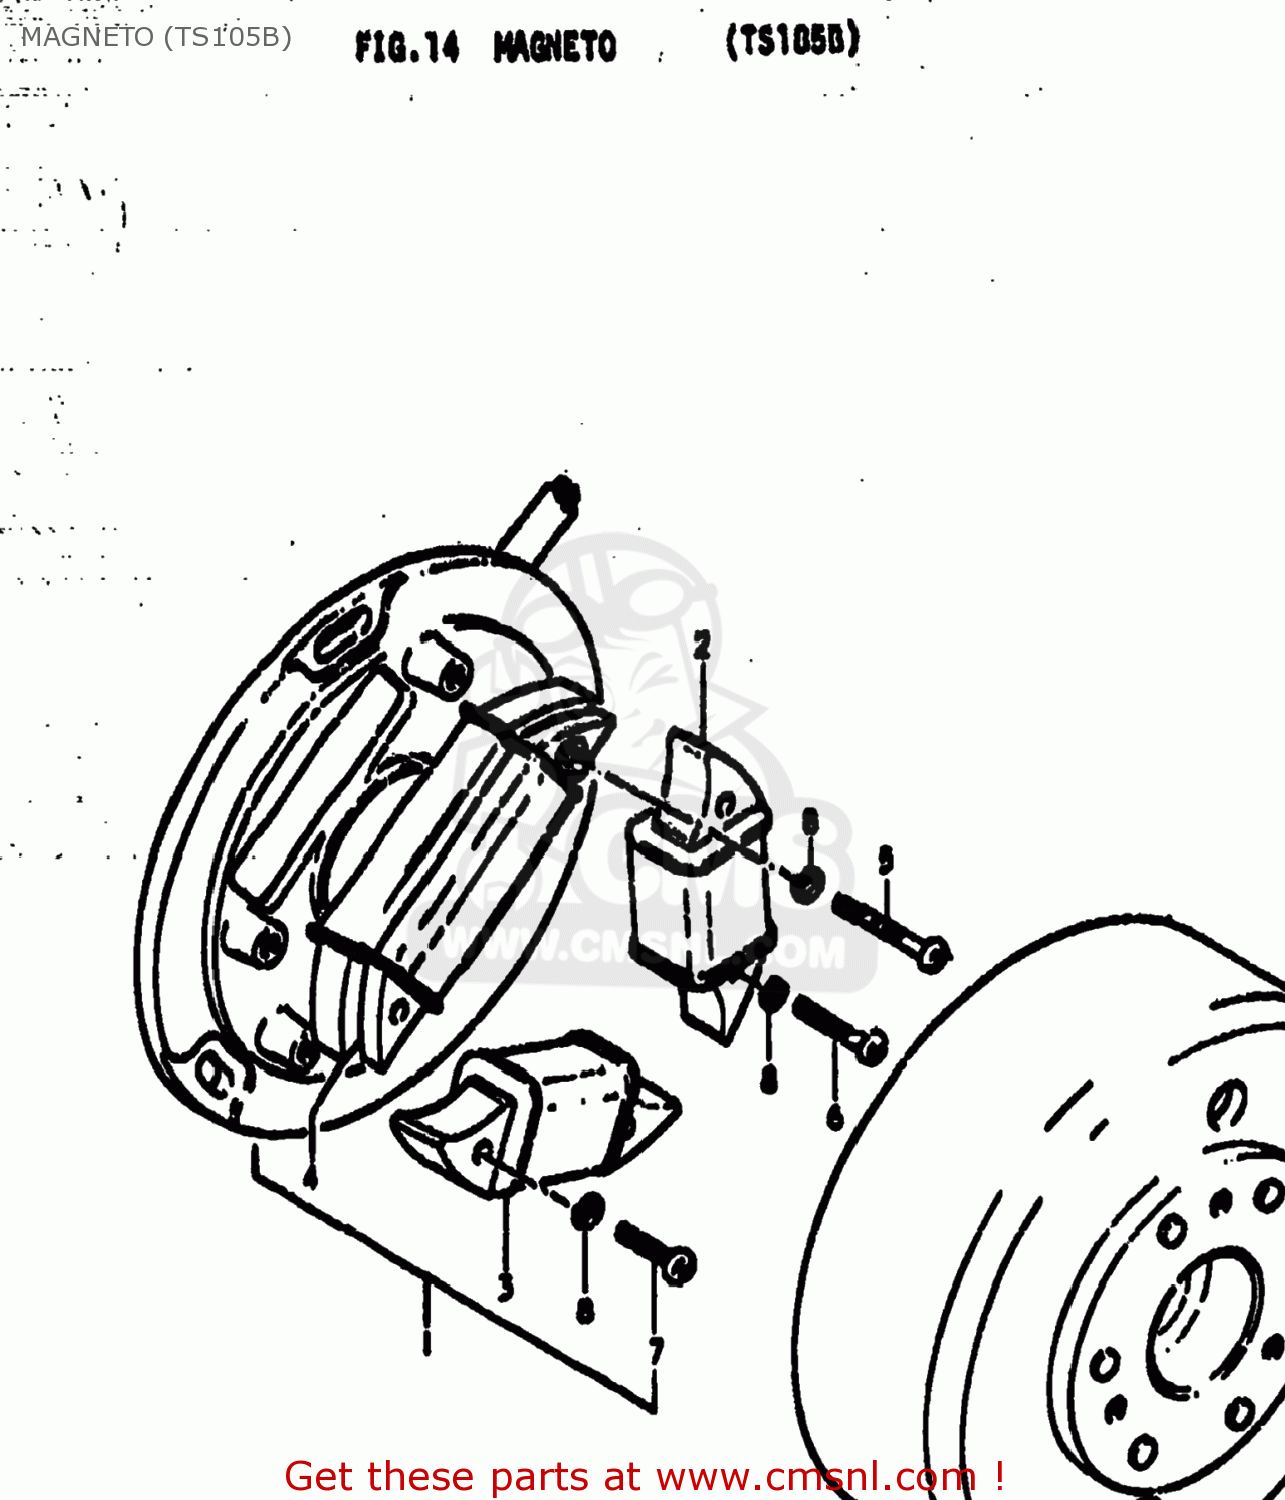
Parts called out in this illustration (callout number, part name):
1	STATOR ASSEMBLY
2	COIL,LIGHTING
3	COIL
4	COIL,IGNITION
5	SCREW
6	SCREW
7	SCREW 5X20
8	LOCK WASHER
9	ROTOR,FLYWHEEL
